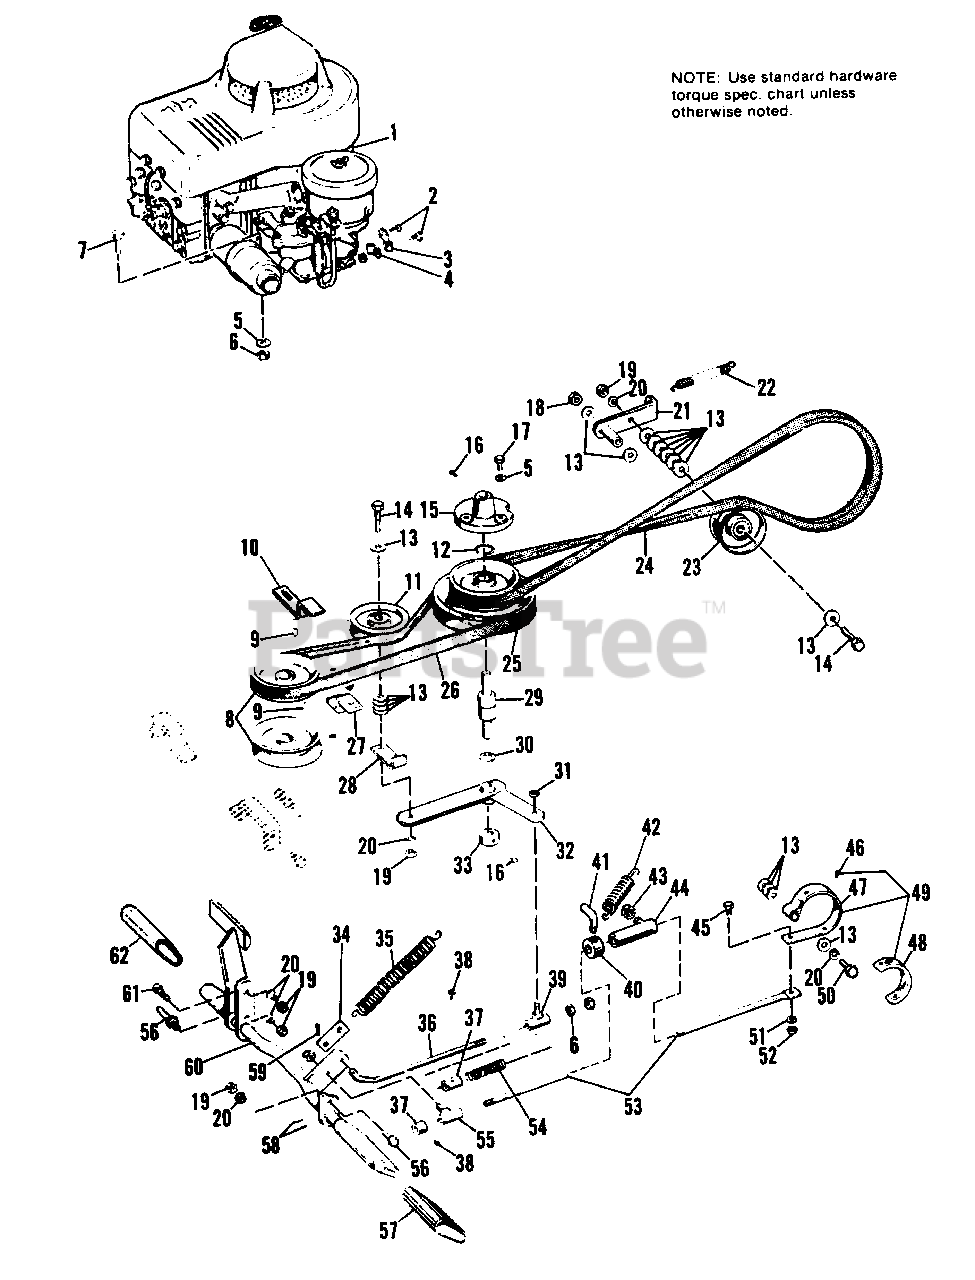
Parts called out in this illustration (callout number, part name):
1	ENGINE, Briggs & Stratton, Power-Kraft Model Type
2	SCREW, Hex, Thread Forming, #10 x 3/8
3	BRACKET, Choke
5	LOCKWASHER, 5/16
6	NUT, Hex, Full, 5/16-18
7	CAPSCREW, Hex Hd., 5/16-18 x 1-1/4
8	PULLEY, Engine
10	STOP, Belt
11	PULLEY, Idler
12	RING, Snap
13	WASHER, Plain, 5/16
14	CAPSCREW, Hex Hd., 3/8-16 x 1-3/4
15	HUB, Pulley Shaft & Bearing
16	SETSCREW, 5/16-18 x 1/2
17	CAPSCREW, Hex Hd., 5/16-18 x 5/8
18	LOCKNUT, Hex, 3/8-16
19	NUT, Hex, Full, 3/8-16
20	LOCKWASHER, 3/8
21	LEVER ASSY., Idler
22	SPRING
23	PULLEY, Idler
25	PULLEY, Double
27	STOP, Belt
28	STOP, Belt
29	SHAFT & BEARING
31	LOCKNUT, Hex, 5/16-18
32	LEVER ASSY., Idler
33	COLLAR, Set
36	ROD, Clutch
37	COLLAR, Set
38	SETSCREW, 1/4-20 x 3/8
39	GUIDE ASSY., Rod
40	COLLAR, Parking Brake
41	LOCK, Parking Brake
43	LOCKNUT, Hex, 1/4-20
44	GUIDE ASSY., Rod
45	CAPSCREW, Hex Hd., 1/4-20 x 1/2
46	RIVET, #7 x 5/16
47	BAND, Brake
48	LINING, Brake
49	BAND ASSY., Brake
50	CAPSCREW, Hex Hd., 3/8-16 x 1-1/2
51	LOCKWASHER, 5/16
52	NUT, Hex, Full, 1/4-20
53	ROD, Brake
55	GUIDE ASSY., Rod
57	COVER, Footrest, L.H.
58	PIN, Roll, 3/16 x 1
59	PIN, Cotter, 3/32 x 3/4
60	SHAFT ASSY, Foot Pedal
61	CAPSCREW, Hex Hd. 3/8-16 x 1
62	COVER, Footrest R.H.
